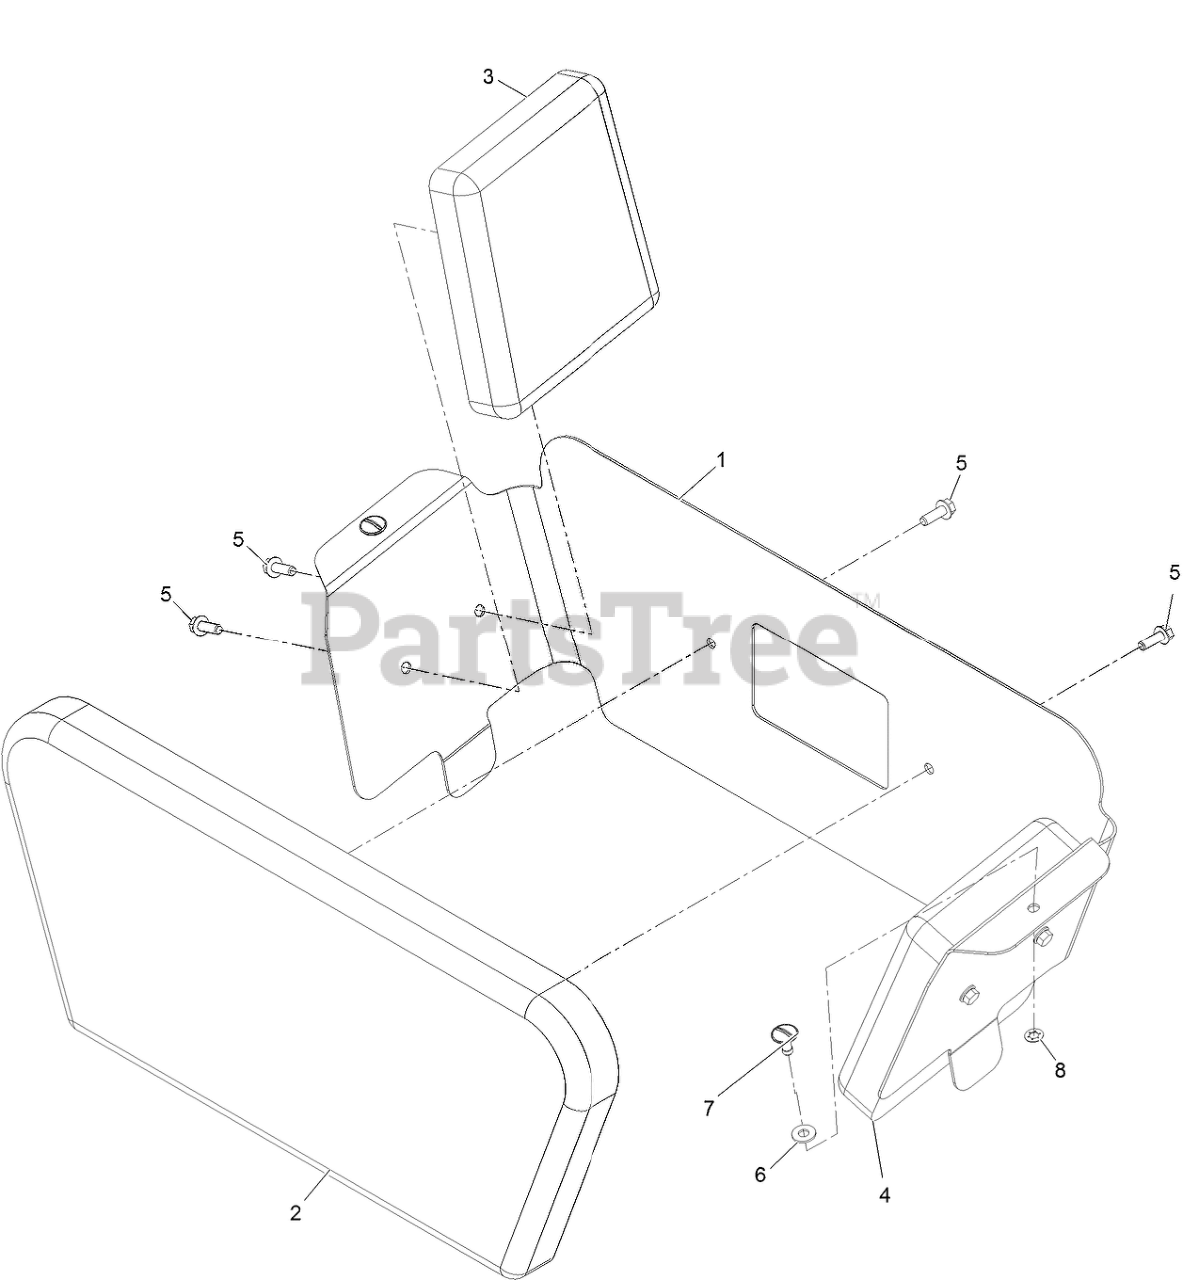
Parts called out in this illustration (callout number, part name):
1	BRACKET-PAD, KNEE
2	Pad-Knee, Center
3	PAD-KNEE, LH SIDE
4	PAD-KNEE, RH SIDE
5	SCREW-HHF
6	WASHER-FLAT
7	STUD-1/4 TURN
8	RETAINER-STUD
